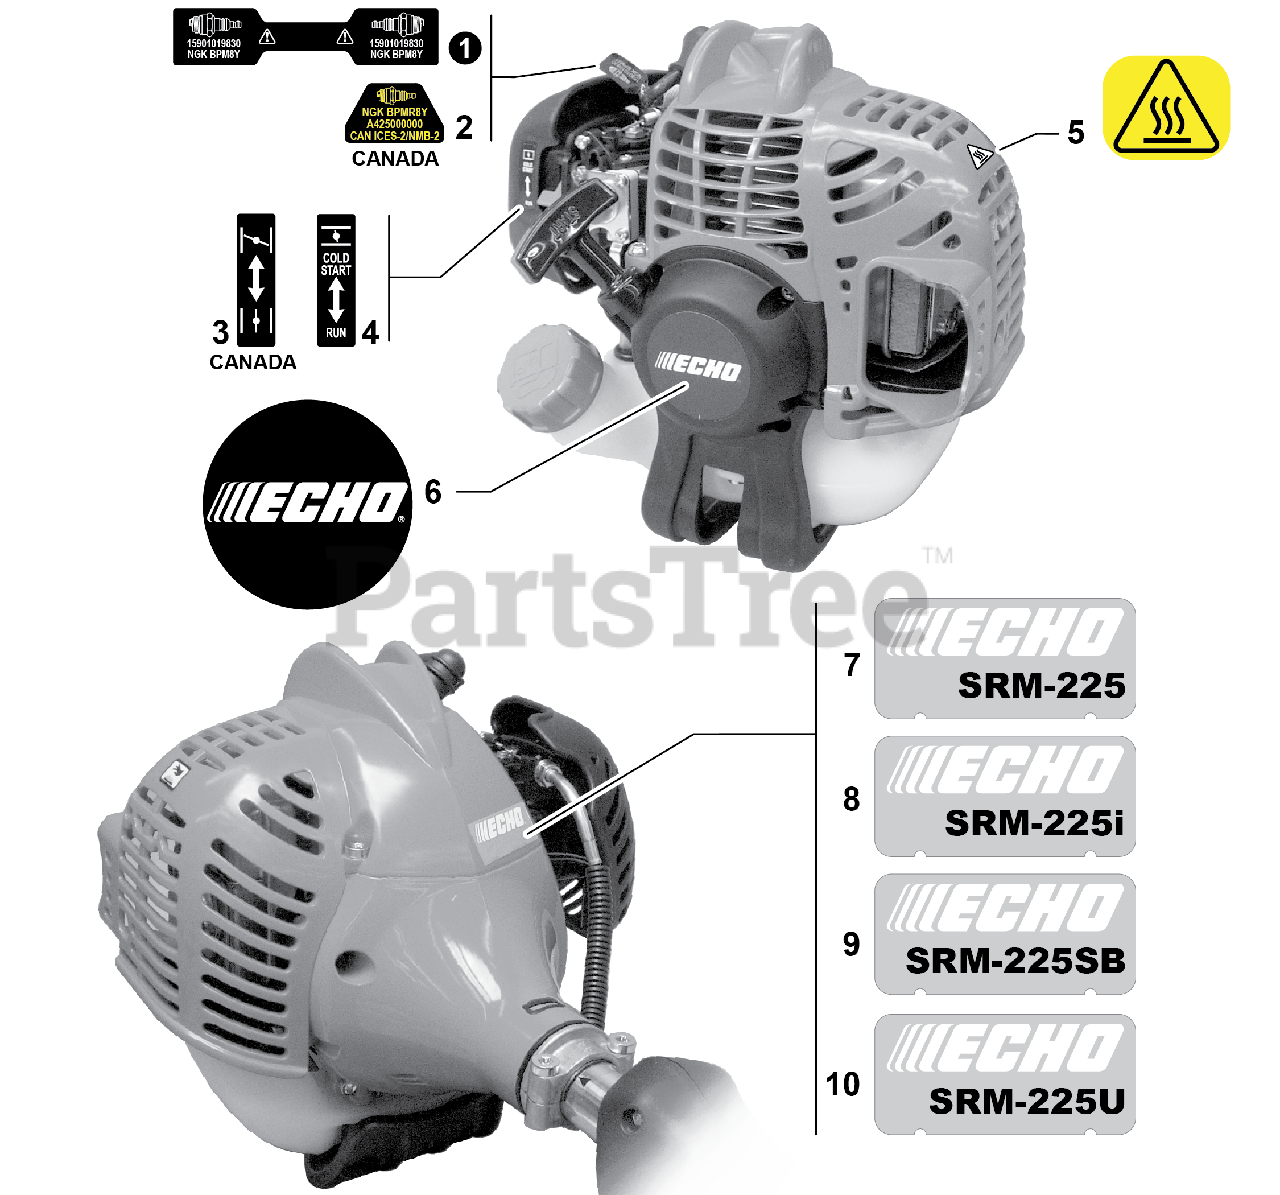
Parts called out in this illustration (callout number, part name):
1	LABEL, SPARK PLUG - BPM8Y
2	LABEL, SPARK PLUG - BPMR8Y
3	LABEL, CHOKE
4	LABEL, CHOKE
5	LABEL, CAUTION - HOT
6	LABEL, RECOIL STARTER
7	LABEL, MODEL SRM-225
8	LABEL, MODEL SRM-225I
9	LABEL, MODEL SRM-225SB
10	LABEL, MODEL SRM-225U
